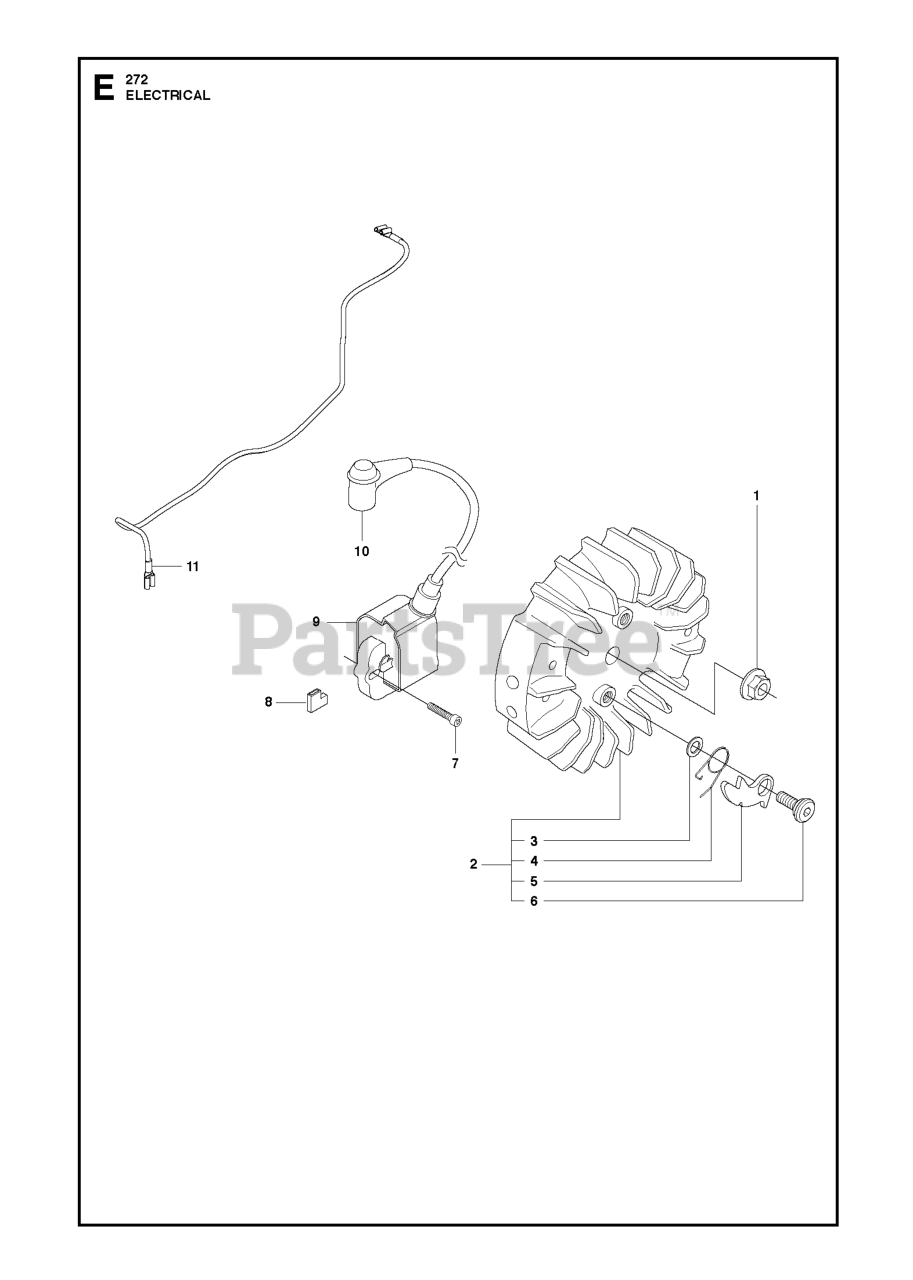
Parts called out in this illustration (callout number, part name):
1	SEAT.TH154.GREY.HUS.ARMREST
2	BRKT.PIVOT.FENDER
3	STRAP
6	NUT
7	SPRING COMPRESSION
8	BOLT.5/16-18UNCX3/4 W/SEMS.BLK
10	PAN.ASM.SEAT.3PT
21	BOLT.SHOULDER.5/16-18
37	NUT.71038.31-18.HEX.NYLOCK
40	HANDLE.SLIDE.SEAT.TEX.BLACK
41	SPRING.LATCH.SEAT.TEX
44	WASHER 13/32 X 2-3/8 X 12GA
